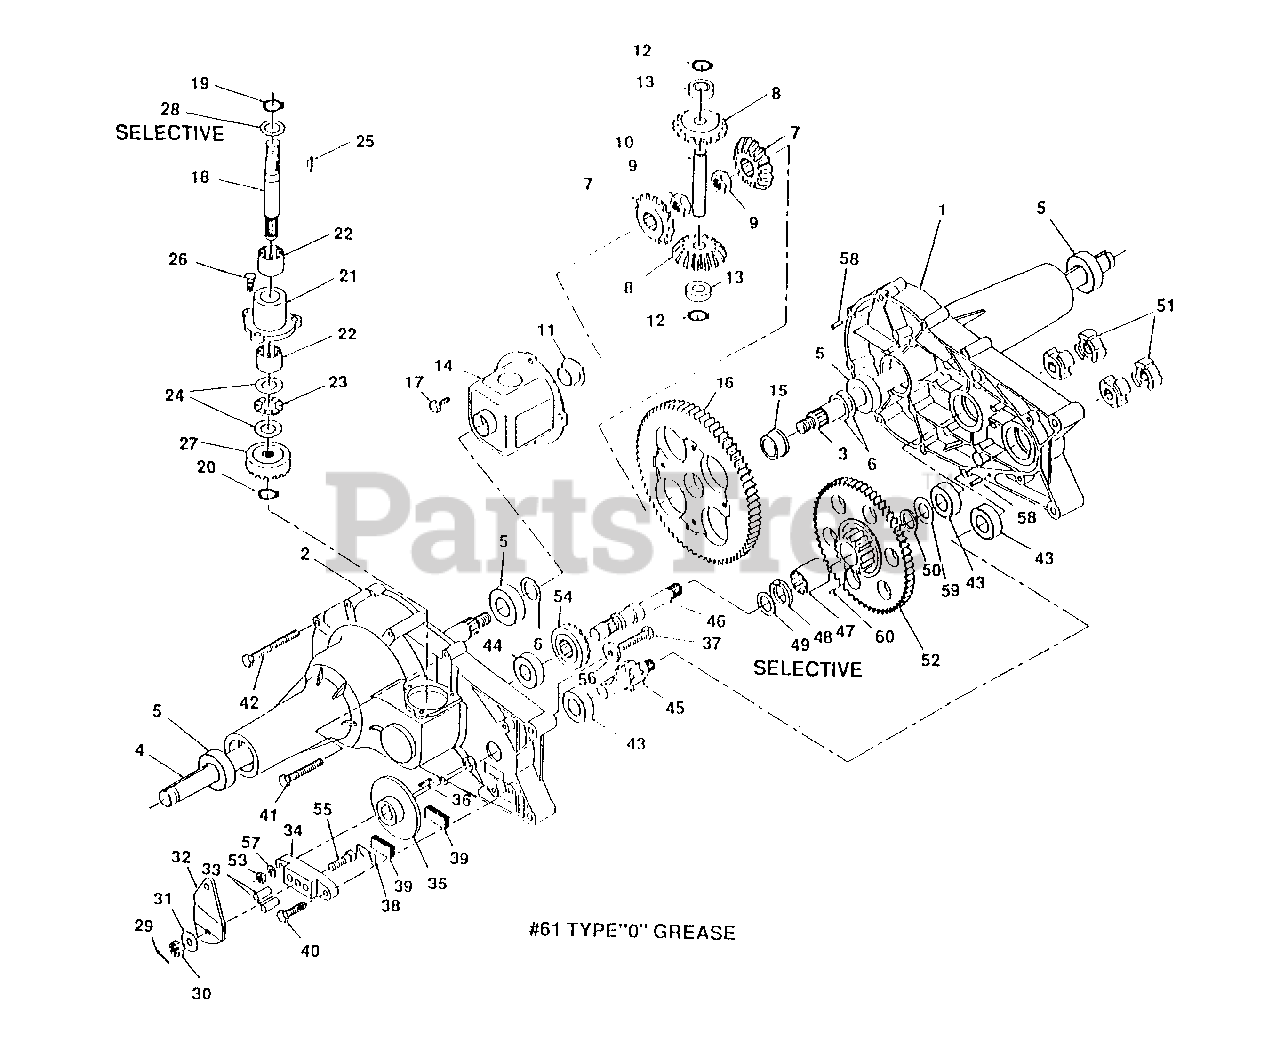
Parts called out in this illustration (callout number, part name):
1	HOUSING HALF L.H.
2	HOUSING HALF RH
5	BEARING, BALL 3/4 ID X 40MM OD X 12 MM
6	WASHER, FLAT 3/4 ID X 1-1/8 OD X .025 THK
7	GEAR, MITER
8	GEAR, MITER
10	SHAFT, CROSS
11	BEARING, FL 3/4 ID X 7/8 OD
12	SNAP RING
13	BEARING, THRUST
14	HOUSING DIFFERENTIAL
15	BEARING, FLANGE
16	GEAR, DIFFERENTIAL 72 TOOTH
17	LOCKING BOLT, 1/4-28 X 9/16" LG
17	ASS'Y,INPUT PINION HSG
18	SHAFT, INPUT
19	SNAP, RING
20	RING. RETAINING 7/16" DIA. EXT.
21	HOUSING, INPUT BEARING
22	BEARING, NEEDLE
23	BEARING, THRUST
24	WASHER, FLAT 5/8 ID X 1-1/4 OD X .030 TH K.
25	KEY, HI-PRO 3/32 X 5/8 DIA.
26	SCREW, HEX W/PATCH 1/4-20 X 3/4 LONG
27	GEAR, INPUT PINION 17 TOOTH
28	WASHER, FLAT .62 ID X 1.0 OD X .050 THK.
28	WASHER, FLAT .62 ID X 1.0 OD X .040 THK.
29	PIN, COTTER
30	NUT, CASTLE 5/16-24
31	WASHER, FLAT .343 ID X .88 OD X .062 THK.
32	ARM, BRAKE ACTUATOR
33	PIN, BRAKE ACTUATING
34	BRAKE, YOKE
35	DISC, BRAKE
36	KEY, HI-PRO 3/16 X 5/8" DIA.
37	SCREW, HEX 1/4-20 X 1.50 LONG
38	PLATE, PUCK
39	PUCK, BRAKE
40	SCREW, HEX W/PATCH 1/4-20 X 1.00 LG
41	SCREW, HEX SELF-TAP 1/4-20 X 2.00 LG
42	SCREW, HEX SELF-TAP 1/4-20 X 3.00 LG
43	BEARING, BALL
43	ASS'Y, HOUSING HALF RH
44	BEARING, BALL
44	ASS'Y, DIFFERENTIAL/AXLE
45	SHAFT, PINION W/11 TOOTH GEAR
46	SHAFT, DRIVE
47	BEARING, NEEDLE
48	BRONZE THRUST BRG 5/8 ID X 1-1/4 OD X 7/64 THK.
49	WASHER, FLAT .62 ID X 1.0 OD X .050 THK.
49	WASHER, FLAT .62 ID X 1.0 OD X .040 THK.
50	GREASE, SEAL BRONZE
51	COUPLING
52	GEAR, 60 AND 17 TOOTH
53	NUT, HEX 1/4-20
54	GEAR, DRIVE PINION 17 T.
55	BOLT, SQUARE HEAD
56	WASHER, 15/16 OD X .265 ID X. 125 THK.
57	WASHER, 1/4" SPRING LOCK
58	PIN, ROLL 3/16" DIA X 1/2" LG
59	WASHER, FLAT .62 ID X 1.0 OD X .030 THK.
60	PIN, DOWEL
61	TYPE "O" GREASE
